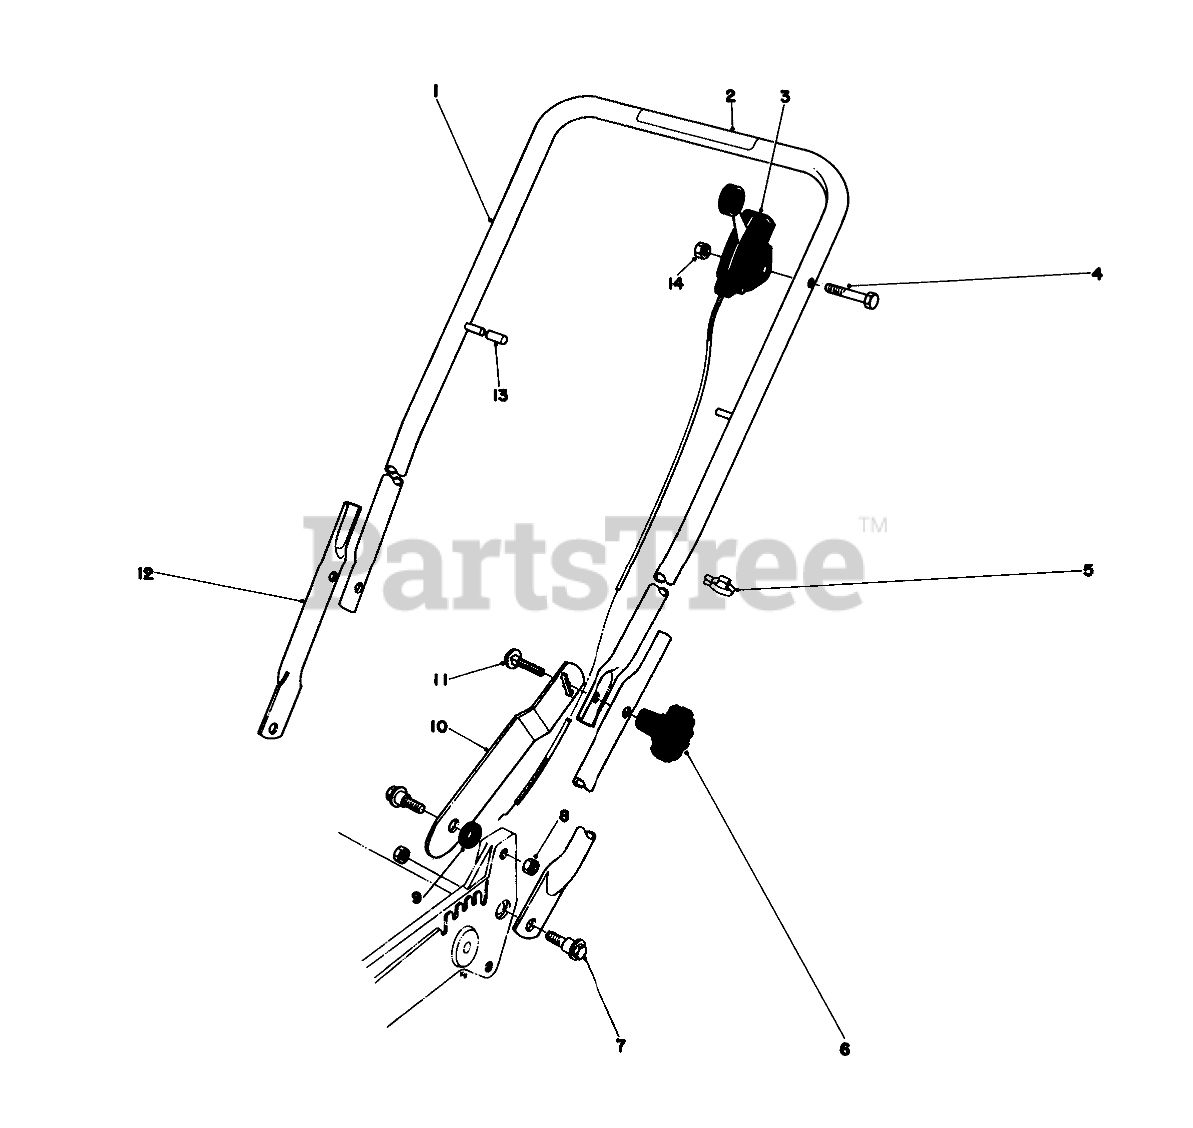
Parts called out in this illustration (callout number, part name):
1	Upper Handle
2	Decal
3	Throttle Control
4	SCREW-HH
5	BOWDEN CLIP
7	Screw
8	Nut
9	SPACER
10	Handle Latch L.H.
11	SCREW-CARR
12	LOWER HANDLE
13	CAP-VINYL
14	NUT-LOCK
